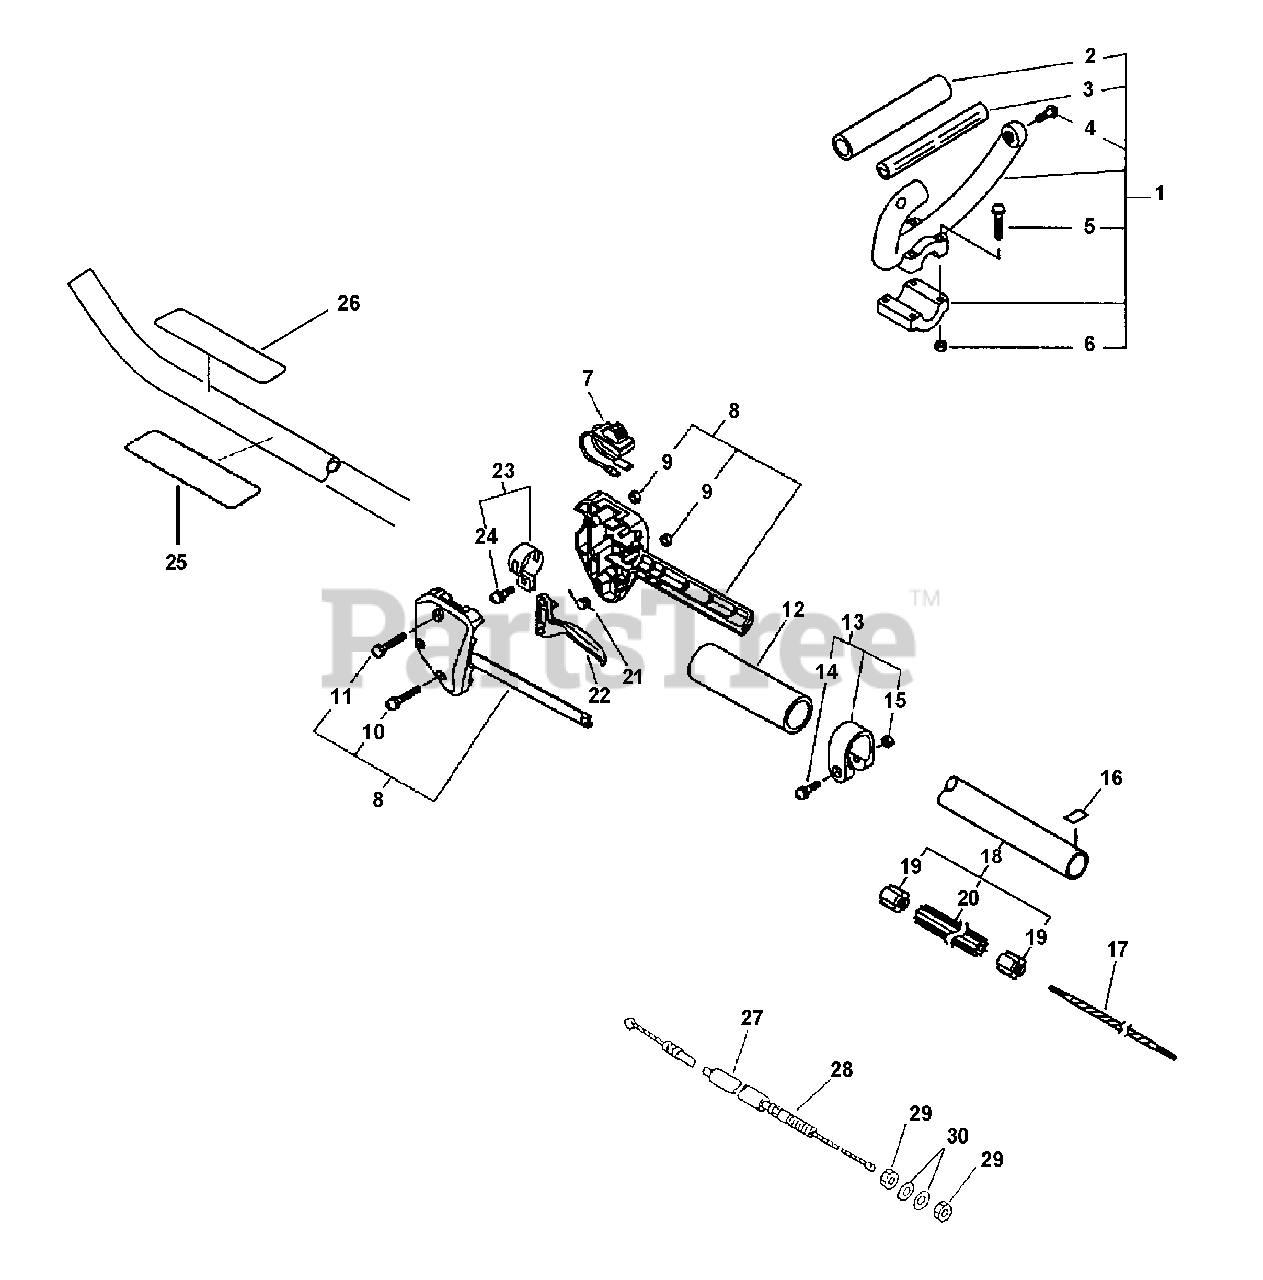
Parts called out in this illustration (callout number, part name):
1	LOOP HANDLE ASSY
2	GRIP, HANDLE
4	SCREW - 5X30
5	SCREW - 5X35
7	IGNITION SWITCH ASSY
8	CONTROL HANDLE KIT
10	SCREW - 5X25
11	SCREW - 5X35
12	GRIP, HANDLE
13	CLAMP KIT
14	SCREW - 5X28
16	LABEL - ALIGNMENT
17	DRIVESHAFT - FLEXIBLE
18	MAIN PIPE ASSY
20	LINER - FLEXIBLE
21	SPRING, TRIGGER
22	TRIGGER, THROTTLE
23	CLAMP KIT
24	SCREW - 5X14
25	LABEL - CAUTION
26	LABEL - CAUTION -- SPANISH
27	TUBE - VINYL
28	CABLE, THROTTLE
30	WASHER - 6
